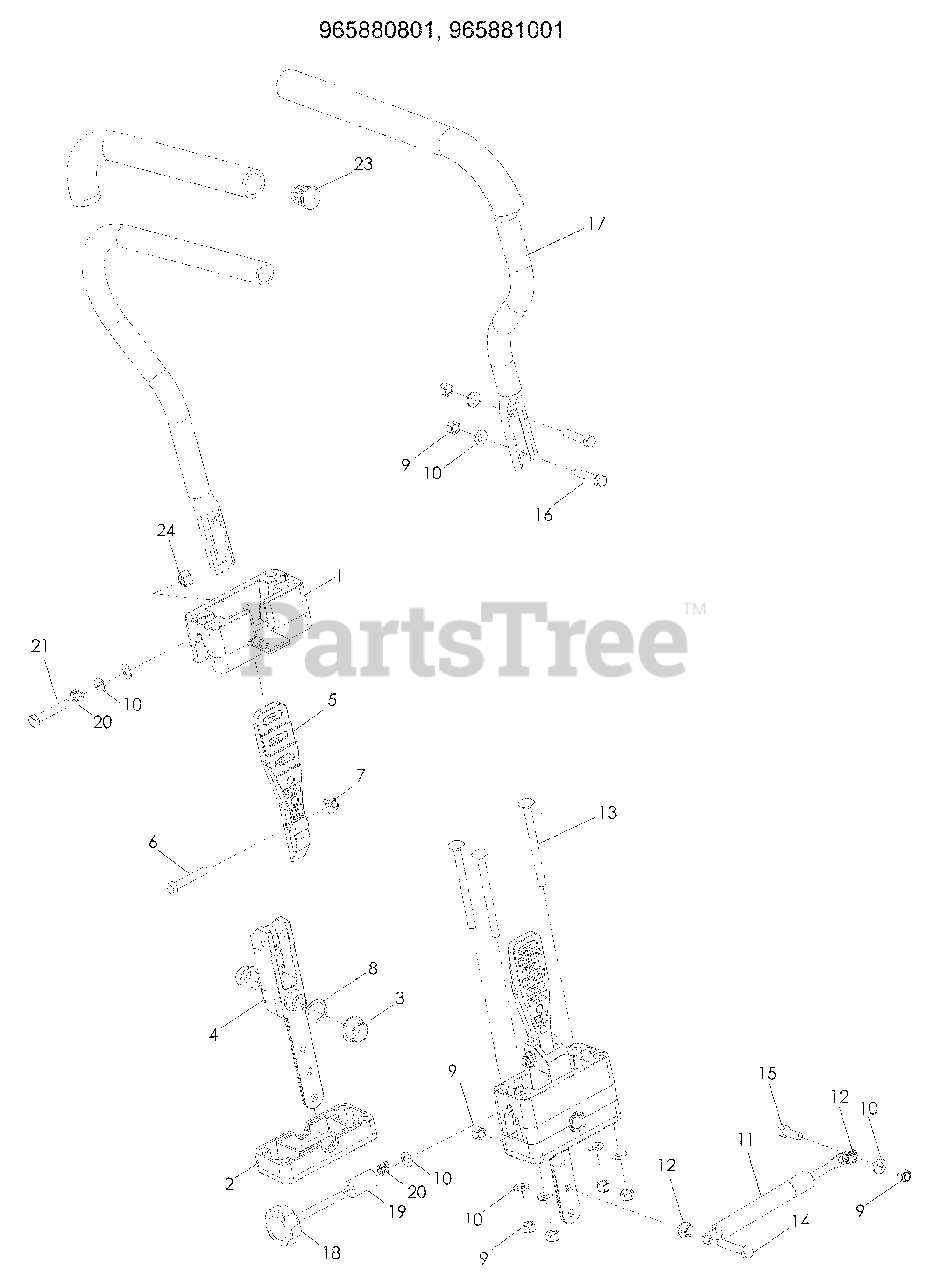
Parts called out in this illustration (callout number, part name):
1	BLOCK, UPPER
2	BLOCK, LOWER
3	BEARING, FLANGE
4	PIVOT SECTION, DRIVE
5	MOUNT, DRIVE CONTROL
6	HCS 5/16-18 x 1¾
7	NUT 5/16-18 FLANGE NYLOC
8	WASHER, .825 x 1.087 WAVE
9	NUT 5/16-18 HEX NYLOC
10	WASHER 5/16 SAE FLAT
12	NUT 5/16-18 HEX WHIZLK
13	RHSNB 5/16-18 x 4
14	HCS 5/16-18 x 1¾ TPBLT
15	HCS 5/16-18 x 1
16	HCS 5/16-18 x 1½
17	LEVER, w/GRIP
21	HCS 5/16-18 x 2 TPBLT
22	GRIP, FOAM
24	NUT 5/16-18 HEX
